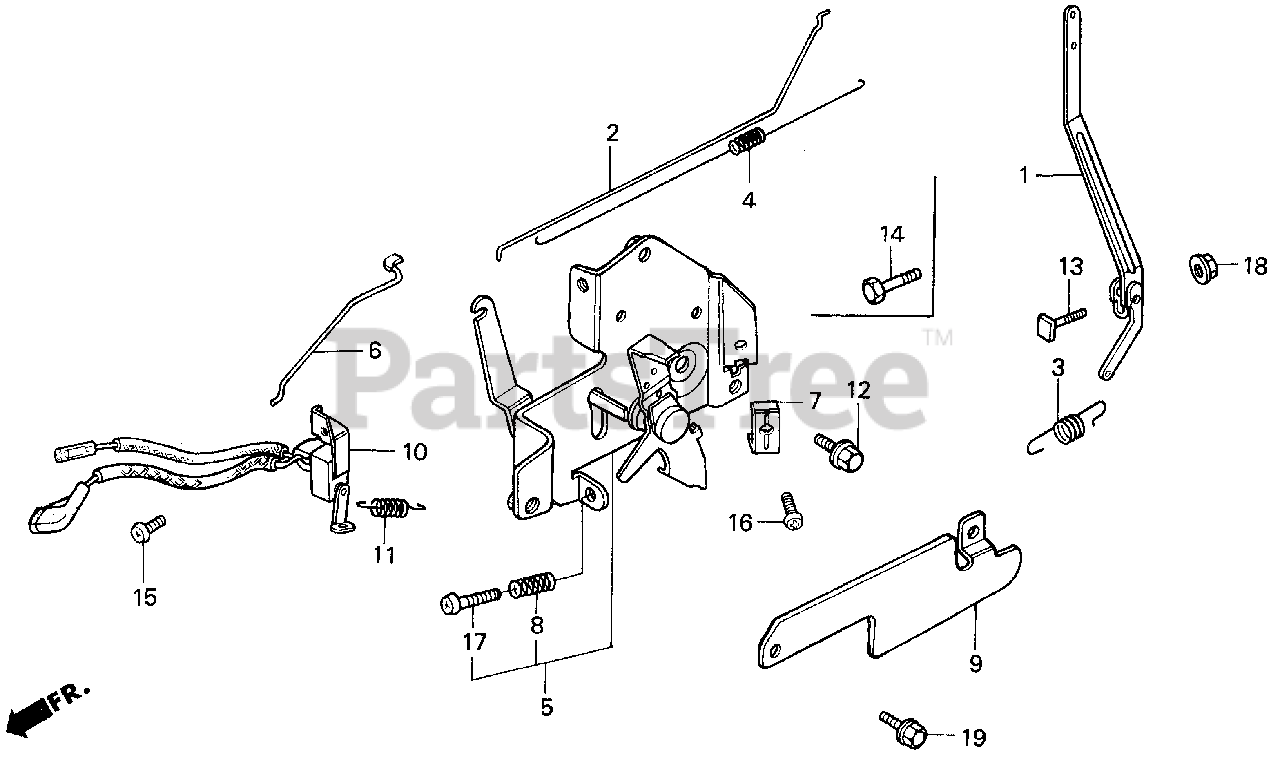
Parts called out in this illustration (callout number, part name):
1	ARM, GOVERNOR
2	ROD, GOVERNOR
3	SPRING, GOVERNOR
4	SPRING, THROTTLE RETURN
5	CONTROL
6	ROD, CHOKE
7	HOLDER, CABLE
8	SPRING, CONTROL ADJUSTING
9	PROTECTOR, CONTROL
10	SWITCH ASSY., ENGINE STOP
11	SPRING, SWITCH CONTROL
12	BOLT, FLANGE (6X14)
13	BOLT, GOVERNOR ARM
15	SCREW, PAN (4X8)
16	SCREW, PAN (5X16)
17	SCREW, PAN (5X20)
18	NUT, FLANGE (6MM)
19	BOLT, FLANGE (6X10)
